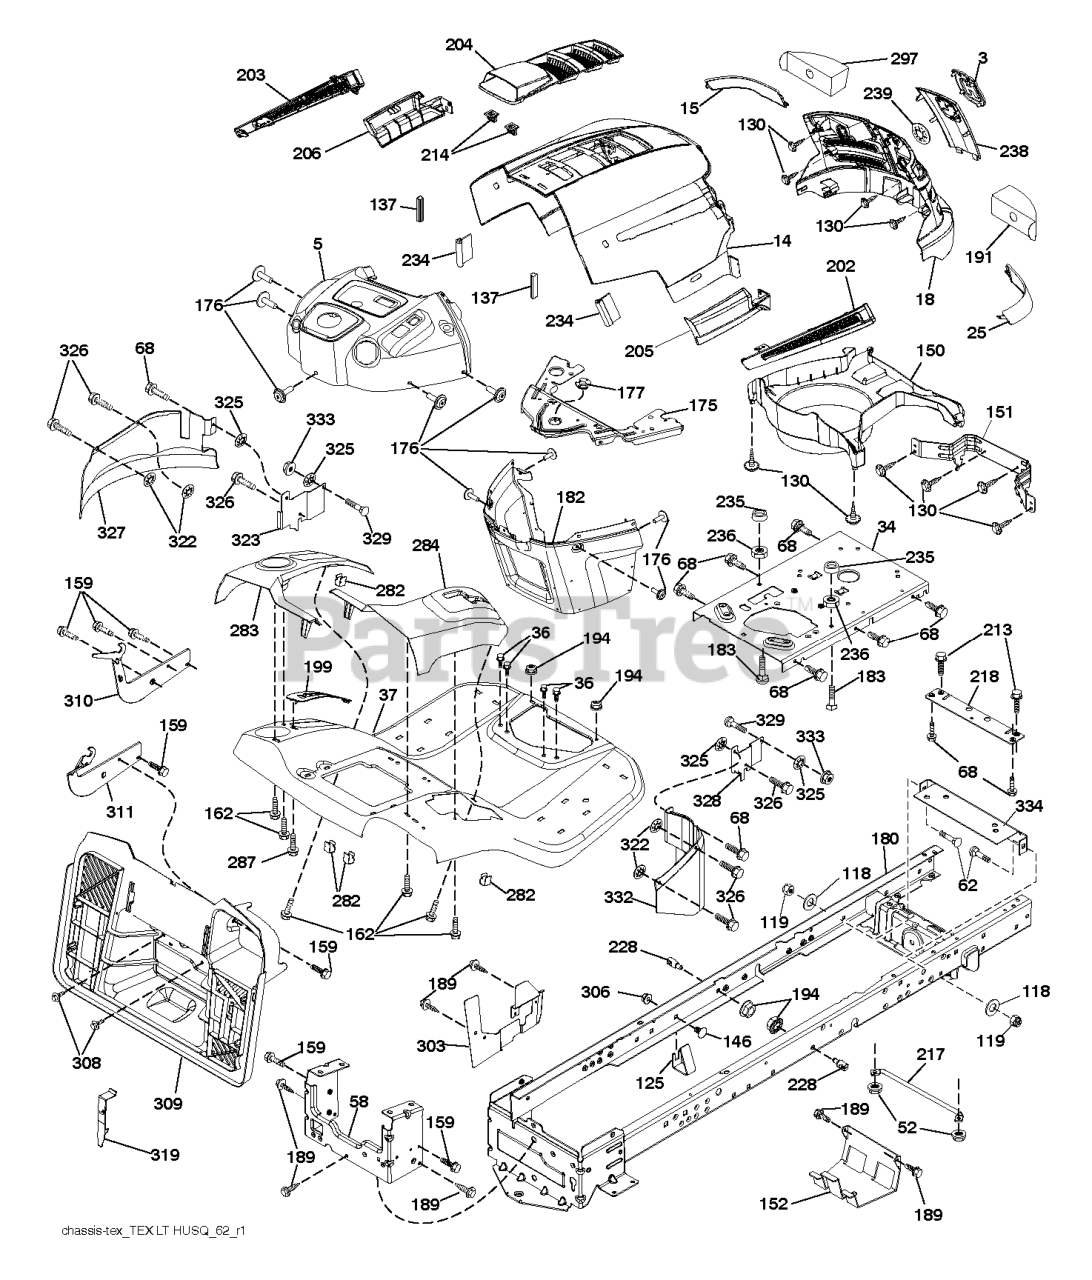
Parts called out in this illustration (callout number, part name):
3	LOGO.HUSQ.GT.LT.CROWN.H
5	SUBASM.DASH.UPPER.HLT.498
14	HOOD.HUSQVARNA.LT.ORANGE
15	LENS.HUSQVARNA LT.RH
18	GRILLE.SVC.HUSQVARNA.GREY
25	LENS.HUSQVARNA LT.RH
34	PLATE.ENGINE.10GA.CRD.GENII
36	SCREW 5/16"
52	LOCKNUT
58	DRAWBAR UPPER 2PC SMALL FENDER
62	BOLT D
68	Screw 5/16-18 x 1/2 Hex, Self Tapping 5/16-18 x 1/2
118	WASHER
125	CLIP.FUEL.LINE
130	SCREW.#10 X 0.750.BOS
137	BUMPER DASH
146	BOLT.RDHD.SHT.SQNK.3/8-16X5/8
151	BRACKET PIVOT
152	SHIELD.BROWNING.W/TEX
159	SCREW, 3/8-16X3/4
162	SCREW.HI-LO.CONSOLE
175	CROSSMEMBER
176	SCREW.#10-24X5/8.RN.QU
177	BUSHING STEERING
180	CHASSIS.WLDMNT.14GA.2PC.18".TI
182	DASH.LOWER.PREDATOR LT
183	BOLT.5/16-18X1-1/4 FULL THD
189	SCREW
191	INSERT.REFLECTIVE.RH.
194	NUT LOCK HEX FLANGE 5/16-18
199	PLATE DECK LIFT
202	VENT.SIDE.HUSQVARNA.LT.RT
203	VENT.SIDE.HUSQVARNA.LT.LFT
204	SUBASM.TOP.VENT.HUSQ.LT
205	SKIRT.SIDE.HUSQVARNA.LT.RT
206	SKIRT.SIDE.HUSQVARNA.LT.LEFT
213	BOLT
214	CLIP.RETAINER.TINNER.
217	ROD.PIVOT.HOOD
218	X-PIECE.HOOD.STOP.NON/
228	STUD.FASTNER.W/ANTI-ROTATE
234	BUMPER.HOOD.TEX.HUSQVARNA
235	SPACER FENDER
236	NUT.CENTERLOCK.5/16-
238	TRIM.HUSQ LT.668
282	CLIP.RETAINER.CONSOLE.LT.HUSQ
283	CONSL.DECKLIFT.LH.SRD.TEX.CRD
284	CONSL.SHFT.PEDAL.RH.SRD.TEXCRD
287	SCREW 1/4X20
297	INSERT REFLECTIVE
303	SHIELD CHASSIS LEFT
306	NUT LOCK FLG 3/8-16 UNC
308	BOLT.5/16-18UNCX3/4 W/SEMS.BLK
309	BACKPLATE.BAGGER.V2.SRD
310	LH.ADJUST.HANGER.BRACKET.ASM
311	RH.ADJUST.HANGER.BRACKET.ASM
319	BRACKET.ACTUATOR.BAGGER.SRD
322	PALNUT 1/4
323	GUARD FRONT LEFT
325	WASHER 5/16"
326	SCREW 14-20 X 5/8
327	GUARD LEFT
328	GUARD FRONT RIGHT
329	BOLT
332	GUARD RIGHT
333	NUT.71038.31-18.HEX.NYLOCK
334	BRACKET.ENGINE
